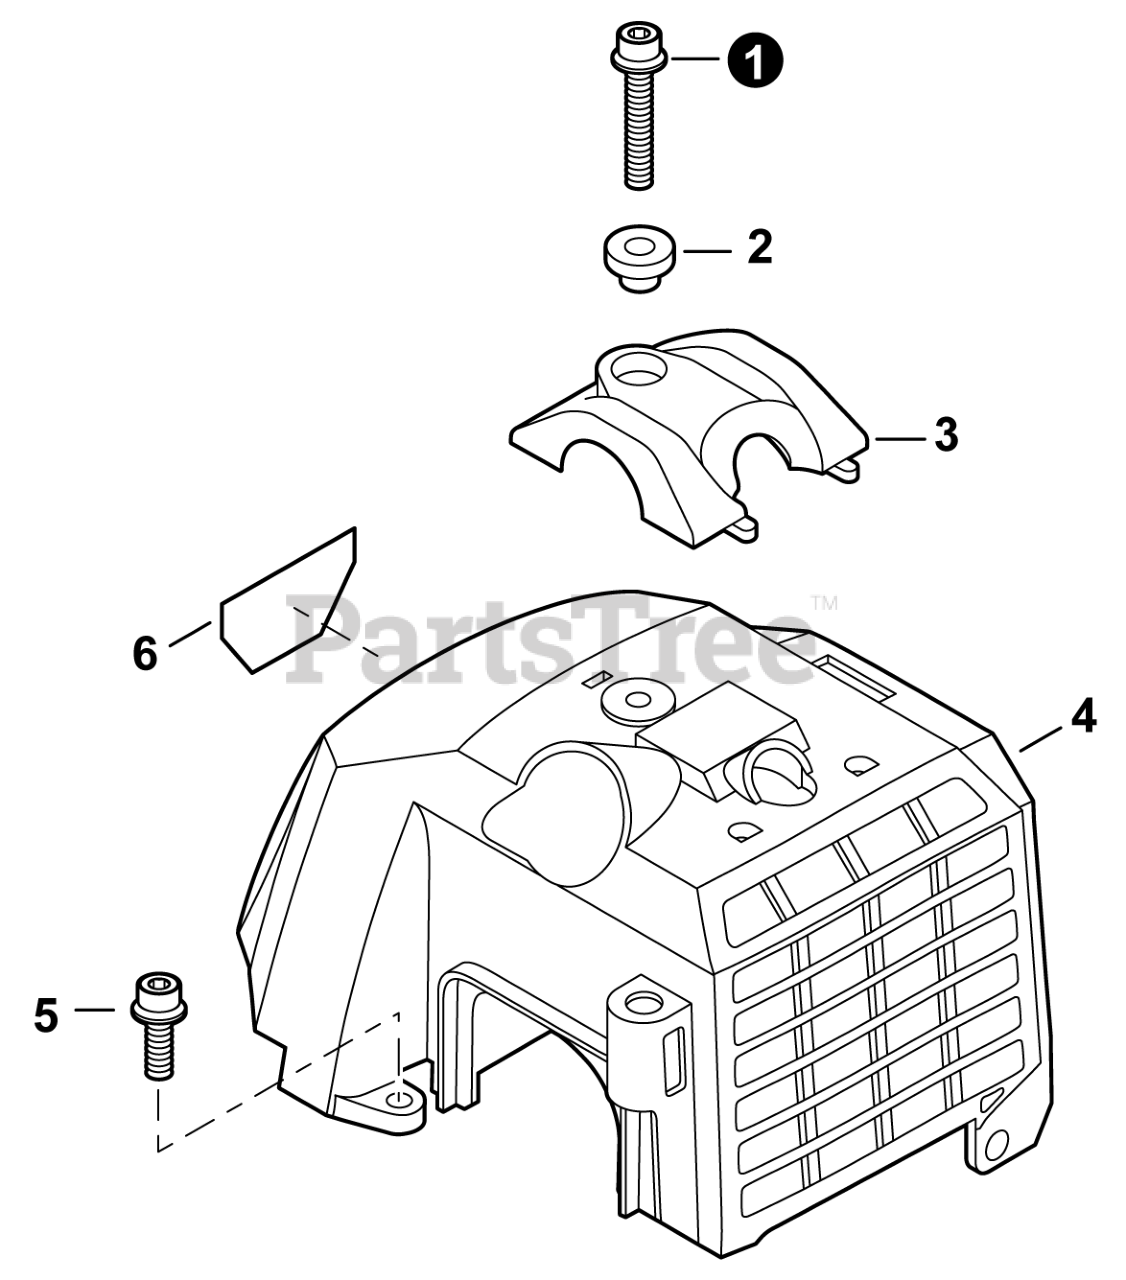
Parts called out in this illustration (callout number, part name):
1	BOLT 5x20
2	COLLAR 5
3	GUARD, TOP
4	COVER, ENGINE
5	BOLT 5x12
6	LABEL - MODEL SRM-4300
